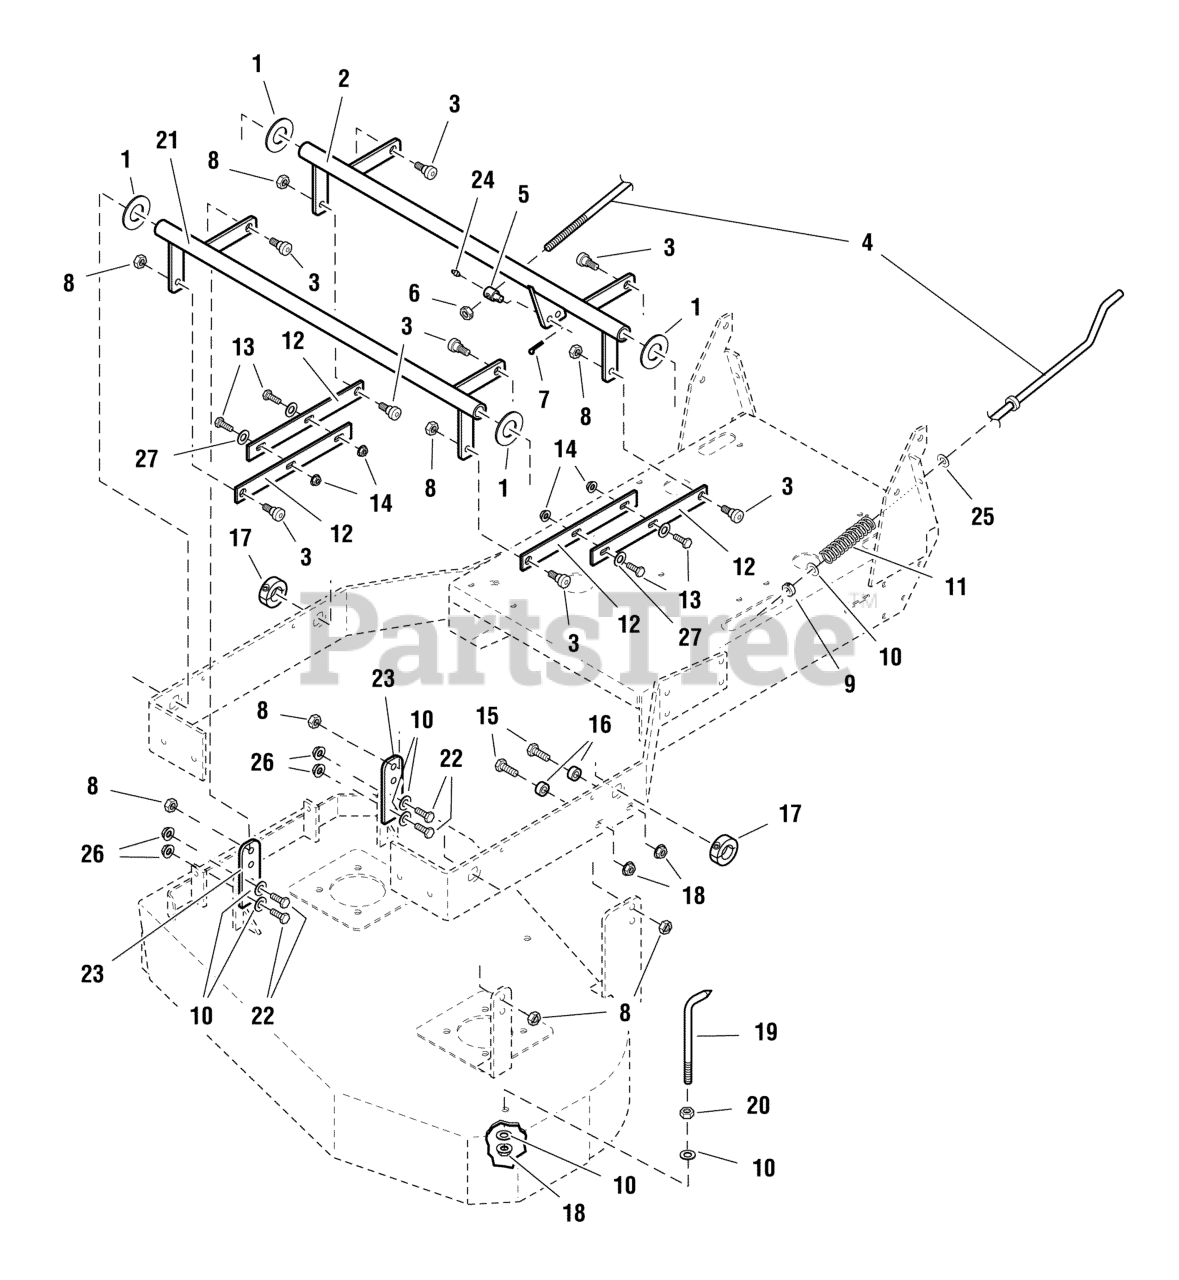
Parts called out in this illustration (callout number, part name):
1	WASHER, 1" SAE
2	DECK LIFT PIVOT - REAR
3	SHOULDER BOLT, 1/2 x 3/8
4	HEIGHT ADJUST ROD
5	LINKAGE ADJUSTER
6	NUT, 3/8-16 Hex Side Lock
7	PIN, 3/32 X 0.750, COT, ZINC/CLEAR
8	NUT, 3/8-16 Hex Top Lock
9	COLLAR, 3/8" Set
10	WASHER, 3/8 SAE
11	SPRING, Compression
12	DECK ADJUST LINK
13	BOLT, 5/16-18 X 1 GD5 YZ
14	NUT, 5/16-18 HEX SERRATED FLANGE (LARGE)
15	BOLT, 3/8-16 X 1-1/4" GD5 CZ
16	SPACER, .39 x .75 x .38
17	COLLAR, Double Split, 1"
18	NUT, 3/8-16 Hex Serrated Flange
19	CUT HEIGHT INDICATOR
20	NUT, 3/8-16 Hex
21	DECK LIFT PIVOT - FRONT
22	BOLT, 3/8-16 X 1" GD5 CZ
23	HANGER PLATE
24	GREASE FITTING
25	WASHER, 3/8" NYLON HYDRO CUT
26	NUT, 3/8-18 Hex NylockFlange
27	WASHER, 5/16" GR.9 FLAT
